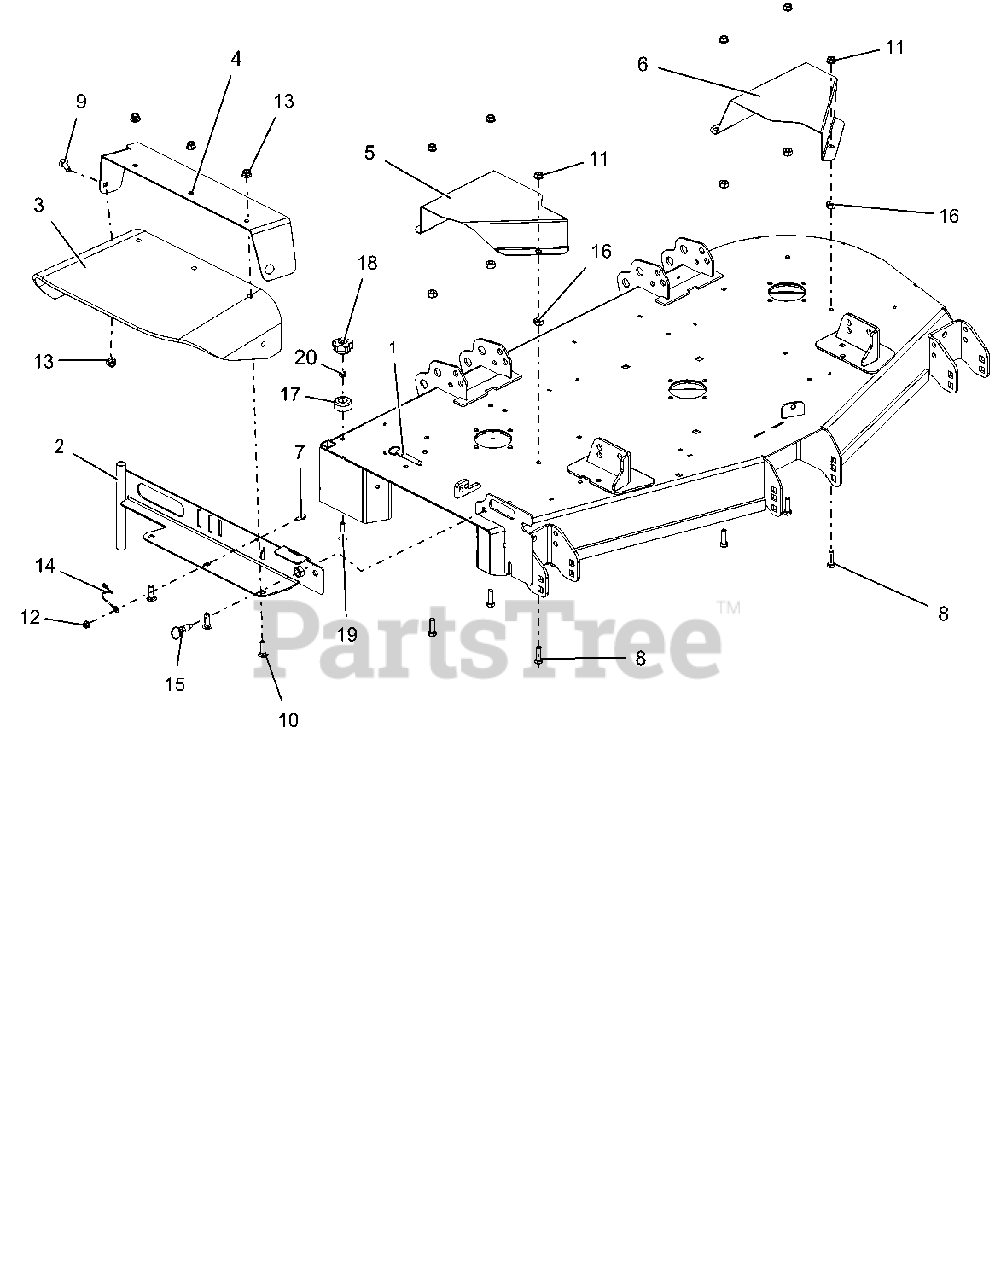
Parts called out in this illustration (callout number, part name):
1	PIN, SPRING BALL .375 OD X 1.50
2	WLDMT, DISCHARGE CHUTE 52"-60"
3	CHUTE, RUBBER DISCHARGE
4	SUPPORT, CHUTE MOUNTING BRKT
5	GUARD, DECK 44"-52" RH (RED)
6	GUARD, DECK 44-52" LH (RED)
7	BLT-HEX .25-20X.75 GR5 YWZC
8	BLT-HEX .38-16X1.25 GR5 YWZC
9	BLT-RDHDSQNK .38-16X1.00 G5 YWZC
10	BLT-RDHDSQNK .38-16X1.25 G5 YWZC
11	@NUT-SPNLK-FLG .375-16 YWZC
12	NUT, LK-TOP-FLG .25-20 YWZC
13	NUT-LK-NYL-FLG .38-16 YWZC
14	CABLE, 6.0 LANYARD, NYLON
15	PULL PIN,.50-13THDX.310 PLNGR
16	NUT-HEAVY HEX .38-16 YWZC
17	BUMPER, RECESSED 1.50 X .63 W/.31 HOLE
18	KNOB, CLAMPING
19	BLT-RDHDSQNK .31-18X1.50 G5 YWZC
20	NUT-LK-CTR .31-18 YWZC
